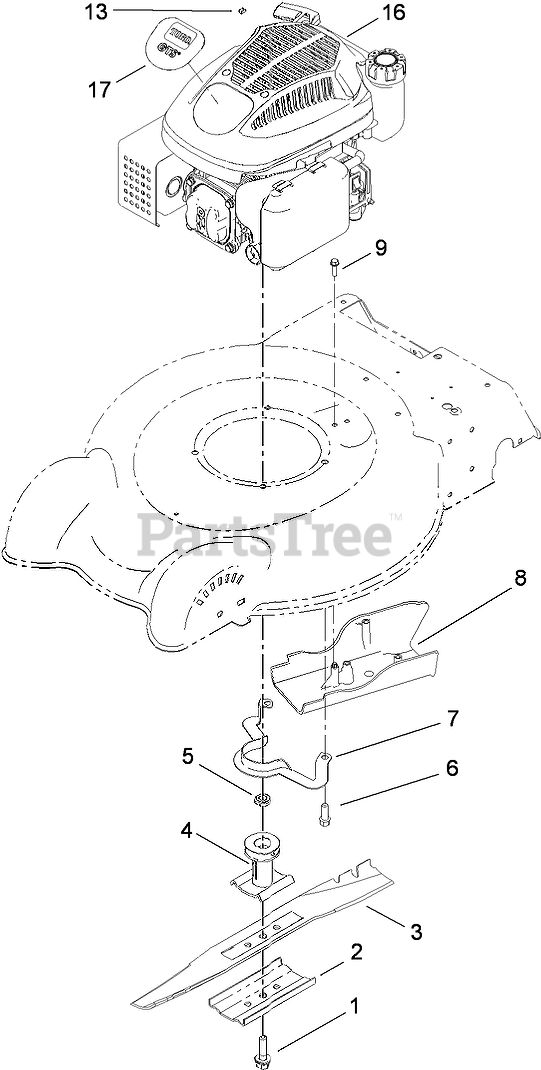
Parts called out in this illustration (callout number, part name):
1	BOLT-BLADE
2	SUPPORT-BLADE
3	BLADE-20 INCH
4	DRIVER-BLADE
5	Spacer-Driver
6	SCREW-TAPTITE
7	Guide-Belt
8	COVER-BELT
9	SCREW-HWH
13	STOP-ROPE
16	ENGINE-LC1P65FA
17	DECAL-ENGINE
